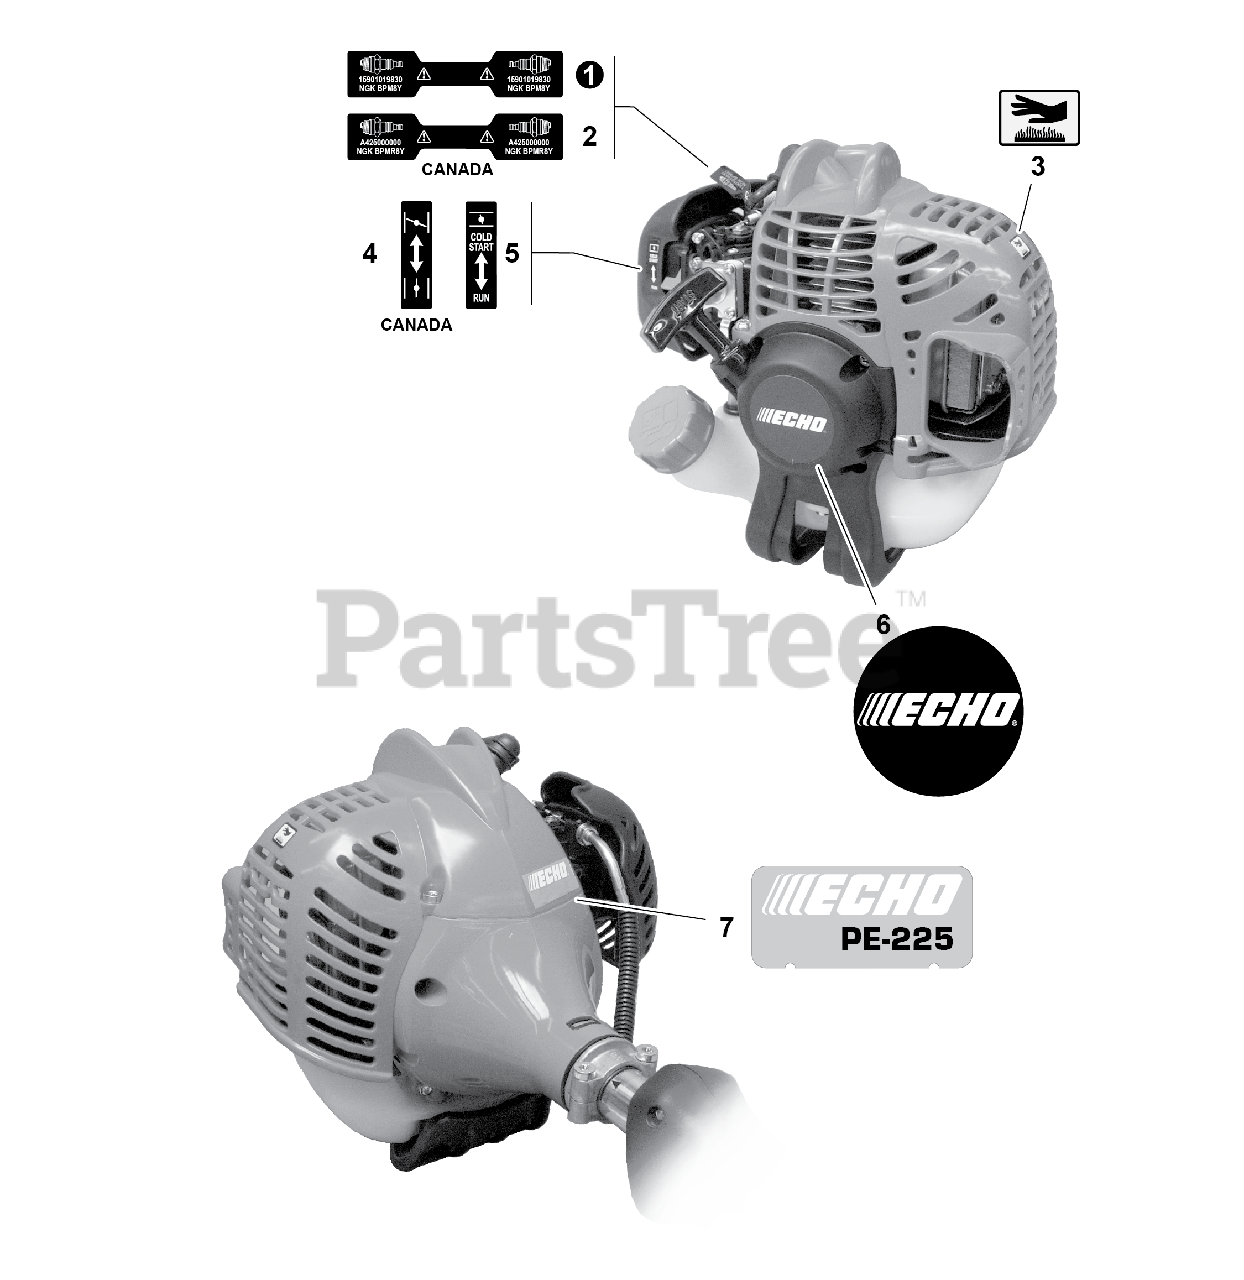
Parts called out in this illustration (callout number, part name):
1	LABEL - SPARK PLUG -- BPM8Y
2	LABEL - SPARK PLUG -- BPMR8Y
3	LABEL - CAUTION -- HOT
4	LABEL - CHOKE
5	LABEL - CHOKE
6	LABEL - ECHO
7	LABEL - MODEL -- PE-225
